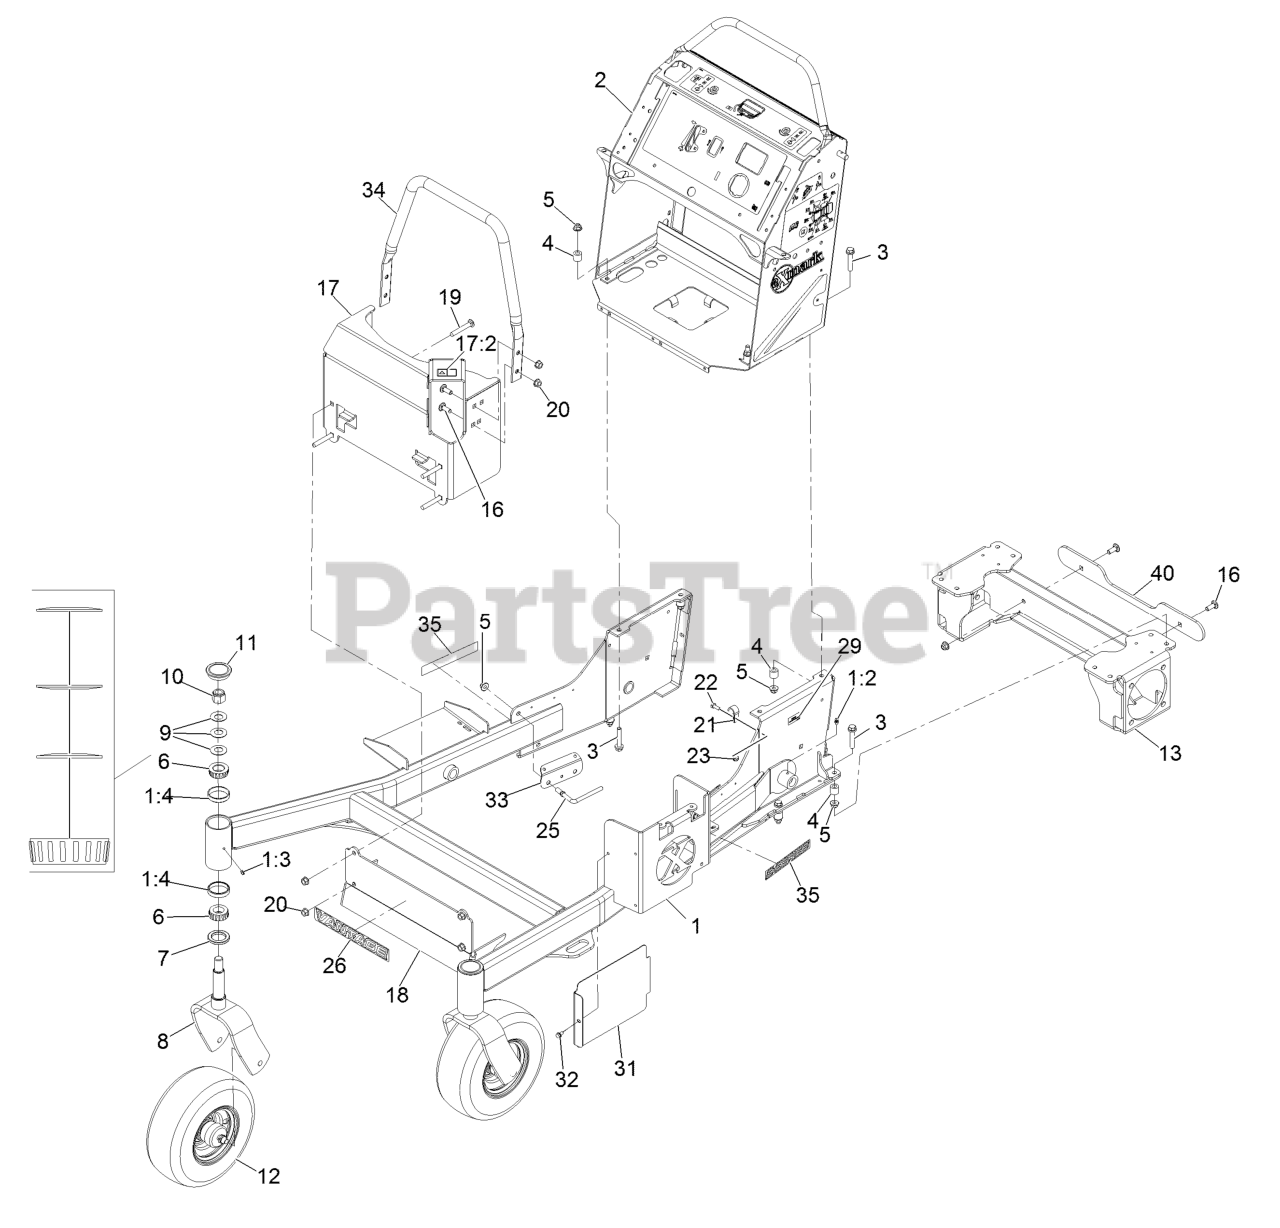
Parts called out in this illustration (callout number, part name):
1	Front Frame ASM
1:2	Zerk 1/4-28 Str Thrd Forming
1:4	Cup-Bearing Tapered Roller
2	ASM-Control Tower
3	Screw-HH Flg 3/8-16 X 2
5	Nut-Nyloc 3/8-16 Flg
6	Cone-Bearing Tapered Roller
7	Seal-Grease
8	Fork-Caster
9	Washer-Spring Disc
10	Nut-Nyloc 3/4-10
11	Cap-Grease
12	Wheel/Tire And Bearing ASM
13	Weld, Motor Frame [black]
16	Bolt-Carriage 3/8-16 X 1
17	ASM, Muffler Guard W/ Decal
17:2	Decal-Warning
18	Panel-Guard
19	Bolt-Carriage 3/8-16 X 2 1/2
20	Nut-3/8-16 Flanged Side Lock
21	Clamp-Cable
22	Screw-HH 1/4-20 X 3/4
23	Nut-Nyloc 1/4-20 Flg
25	Guide-Hose, Support
26	Decal-Vantage Logo
29	Decal-Patent
31	Shield-Heat, Tall
32	Screw-HWH 1/4-20 X 1/2 Taptite
33	Guard-Hose
34	Tube-Guard
35	Decal-S-Series
40	Plate, Bumper Spacer
